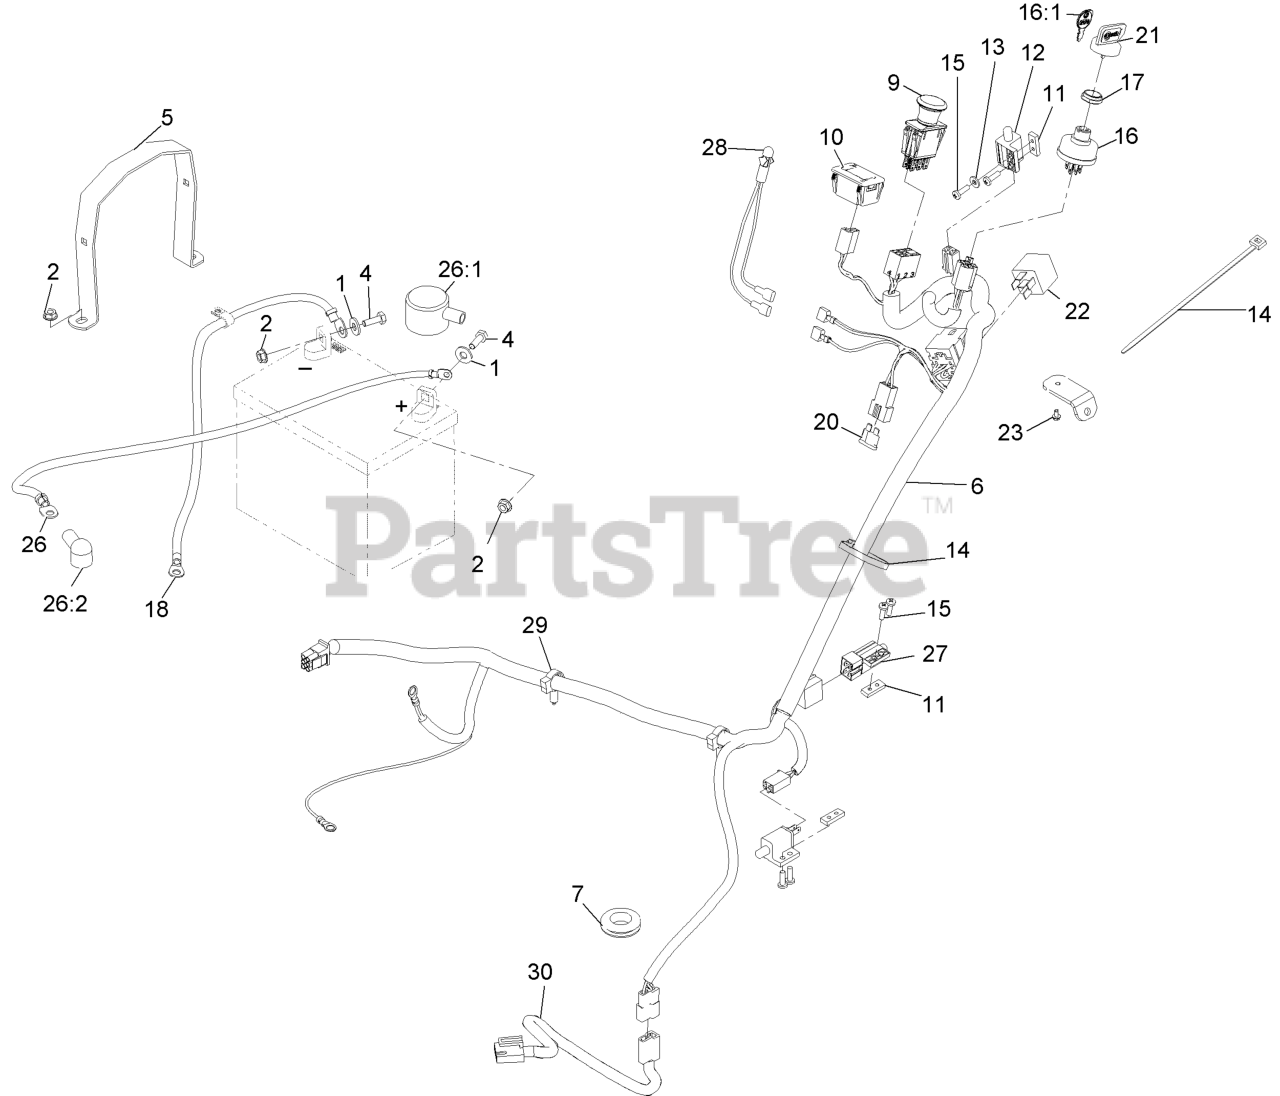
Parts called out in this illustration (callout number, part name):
1	WASHER-FLAT
4	SCREW-HH
5	STRAP,BATTERY HOLDDOWN
6	HARNESS-WIRE
7	GROMMET
9	SWITCH-PTO
10	HOURMETER
11	PLATE-TAPPED
12	SWITCH-OPEN, NORMALLY
13	WASHER-FLAT
14	TIE-PLASTIC
15	SCREW-PPH
16:1	KEYS-IGNITION (SPARE PAIR
17	NUT-SWITCH, IGNITION
18	WIRE-GROUND
20	FUSE-BLADE TYPE, 20 AMP
21	KEY-IGNITION
23	SCREW-HWH
26	POSITIVE BATTERY CABLE AS
26:1	INSULATOR-BATTERY
26:2	INSULATOR-SOLENOID
27	SWITCH-BRAKE
28	INDICATOR-LED, RED
29	Clip-Harness
30	HARNESS-CLUTCH PIGTAIL
